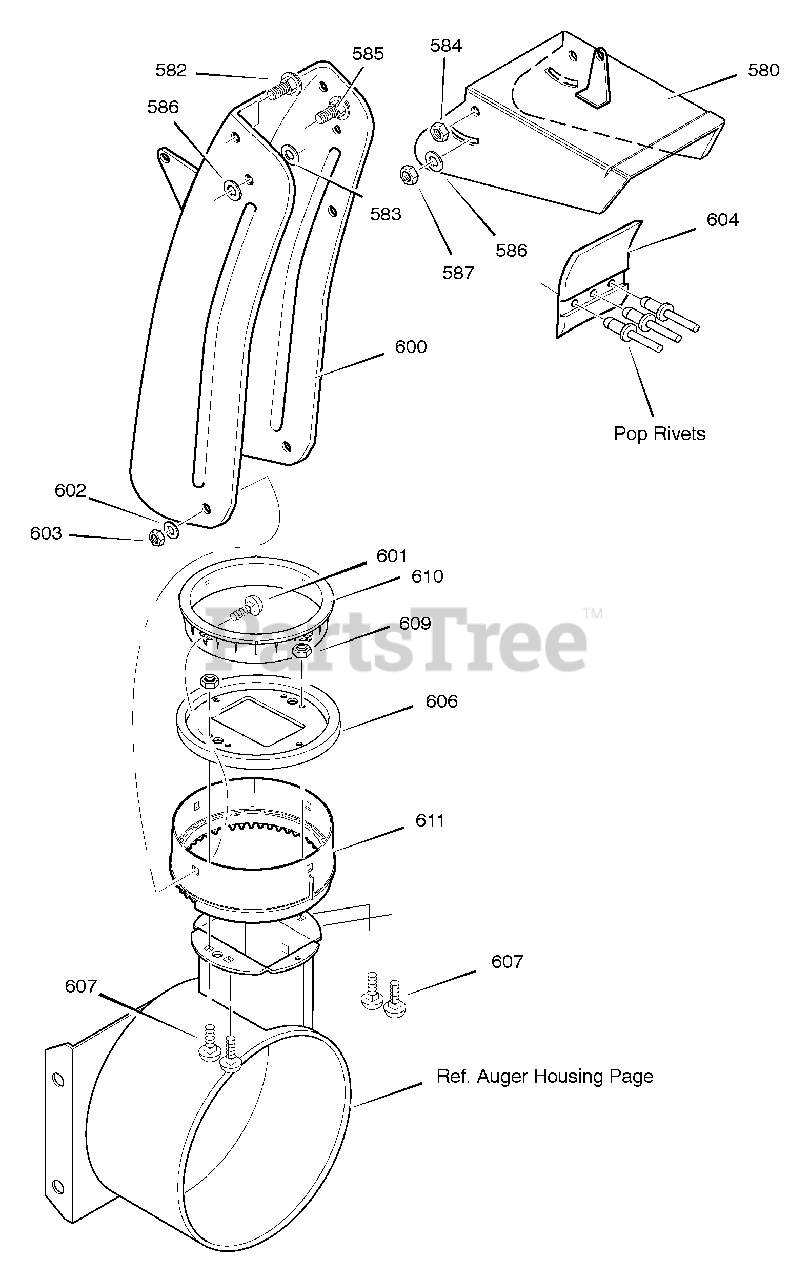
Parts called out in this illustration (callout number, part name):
580	CHUTE, UPPER W/REMOTE
582	SCREW, 5/16-18 x 0.75
583	WASHER, PLASTIC
584	NUT
585	SCREW, 5/16-18 x 0.75
586	WASHER, PLASTIC
587	NUT
600	CHUTE, LOWER W/REMOTE
601	CARRIAGE BOLT, 5/16-18 x 1
602	WASHER, FLAT
603	NUT
604	FLAP
606	CHUTE COLLAR
607	BOLT
609	NUT
610	RETAINER, RING INNER
611	RETAINER, RING OUTER
